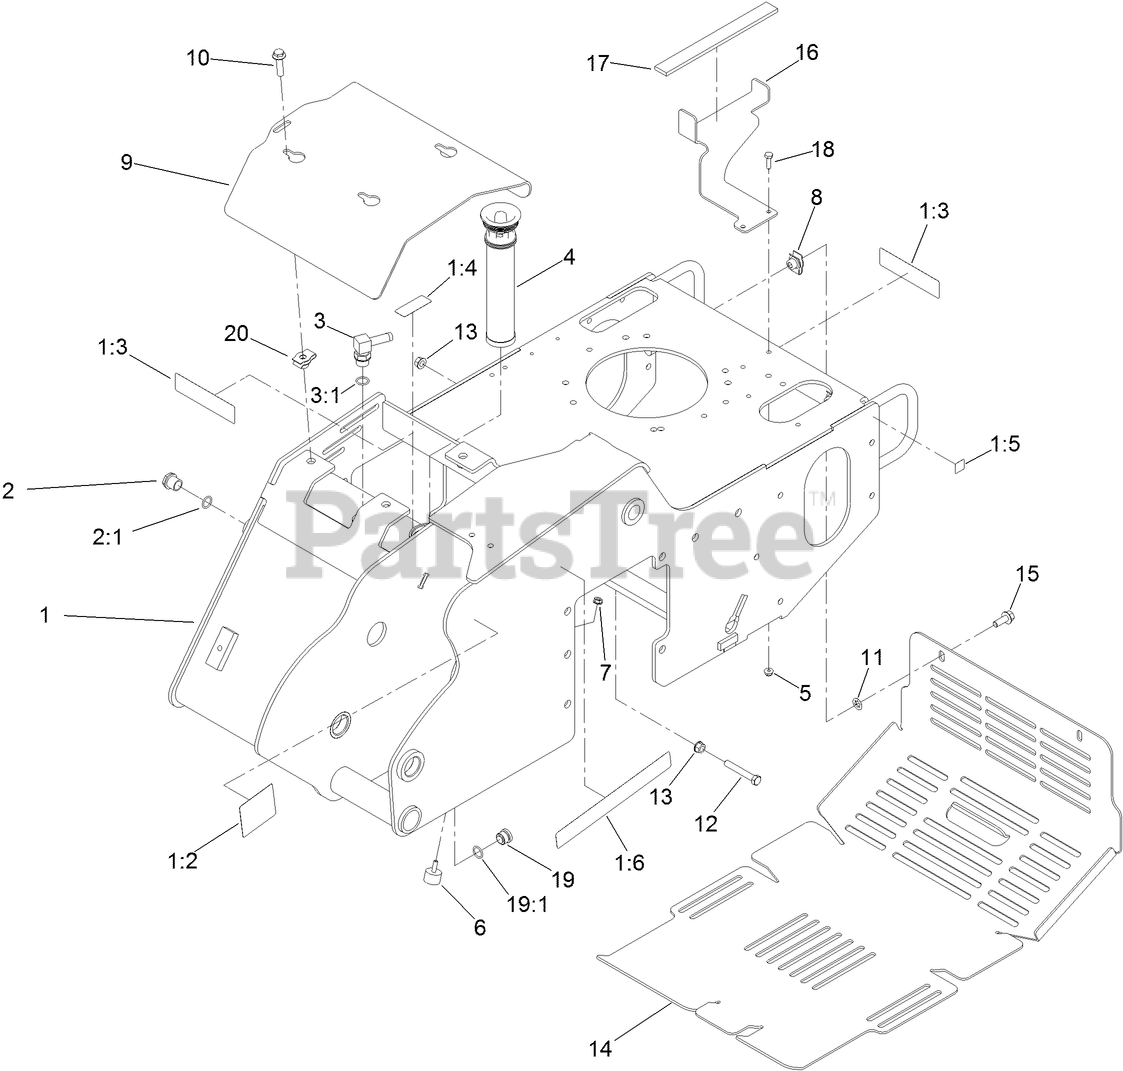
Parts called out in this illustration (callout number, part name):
1	MAIN FRAME ASM
1:2	DECAL-WARNING
1:3	DECAL-DANGER
1:4	DECAL-OIL, HYD
1:5	DECAL-POINT, LIFT
1:6	DECAL-INTELLITRENCH
2	SIGHT GLASS ASM
2:1	O-RING
3	FITTING-ELBOW, 90
3:1	O-RING
4	IN-TANK FILTER ASM
5	NUT-HF
6	BUMPER
7	NUT-HF
8	NUT-TINNERMAN
9	PLATE-COVER, FRONT
10	SCREW-HHF
11	NUT-PUSH
12	SCREW-HH
13	NUT-FLANGE
14	COVER-REAR
15	SCREW-HHF
16	BRACKET-TANK
17	PAD-FOAM
18	SCREW-HH
19	PLUG ASM
19:1	O-RING
